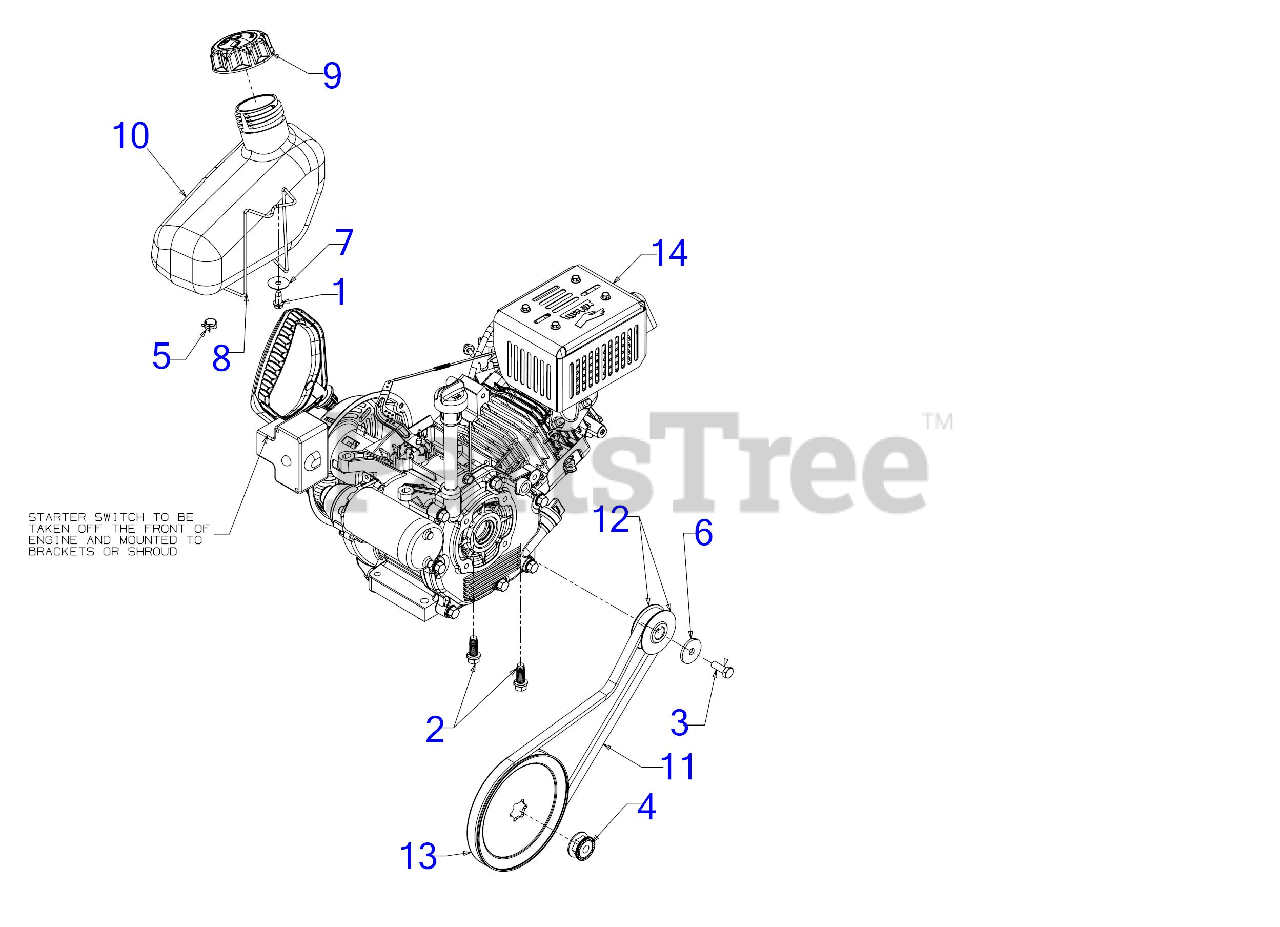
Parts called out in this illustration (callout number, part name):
1	SCREW 1/4-10:.625
2	SCREW 3/8-16 x 1
3	SCREW 5/16-24 x .875 GR5
4	FLANGE NUT W/HUB
5	HOSE CLAMP 1/20
6	WASHER-5/16 x 1.25X 1.27
7	FLAT WASHER
8	SUPPORT WIRE
9	FUEL CAP THREAD VENT
10	FUEL TANK (2 QT)
11	V-BELT .500 x 35.
12	HALF PULLEY
13	AUGER PULLEY
14	179CC COMPLETE ENGINE
